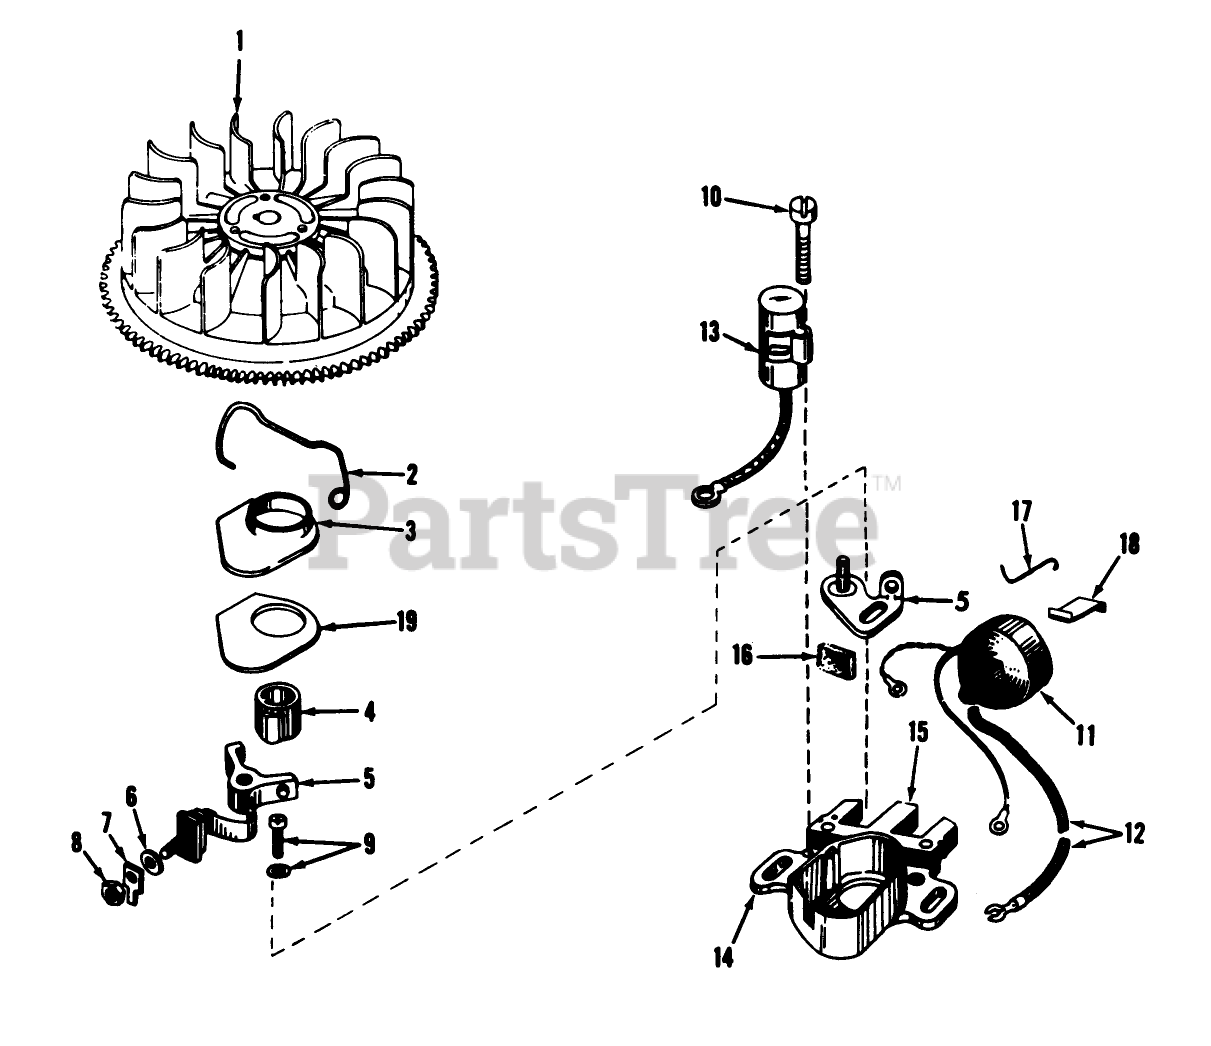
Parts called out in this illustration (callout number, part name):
1	Flywheel
2	Spring Breaker Box
3	Cover, Dust
4	Cam-Breaker
5	Breaker Assy.
6	Washer
7	Terminal, Ground
8	DECAL
9	Breaker Screw
10	Condenser Screw
11	Coil Assy. (Incl. No. 12)
12	Wire, Lead
13	Condenser
14	Core Plate
15	Stator Assy., (Incl. Nos. 2, 3, 5 thru 14 16 thru 19)
16	Felt,Cam Wiper
17	Clip, Coil
18	Spring Coil Wedge
19	Gasket, Dust Cover
